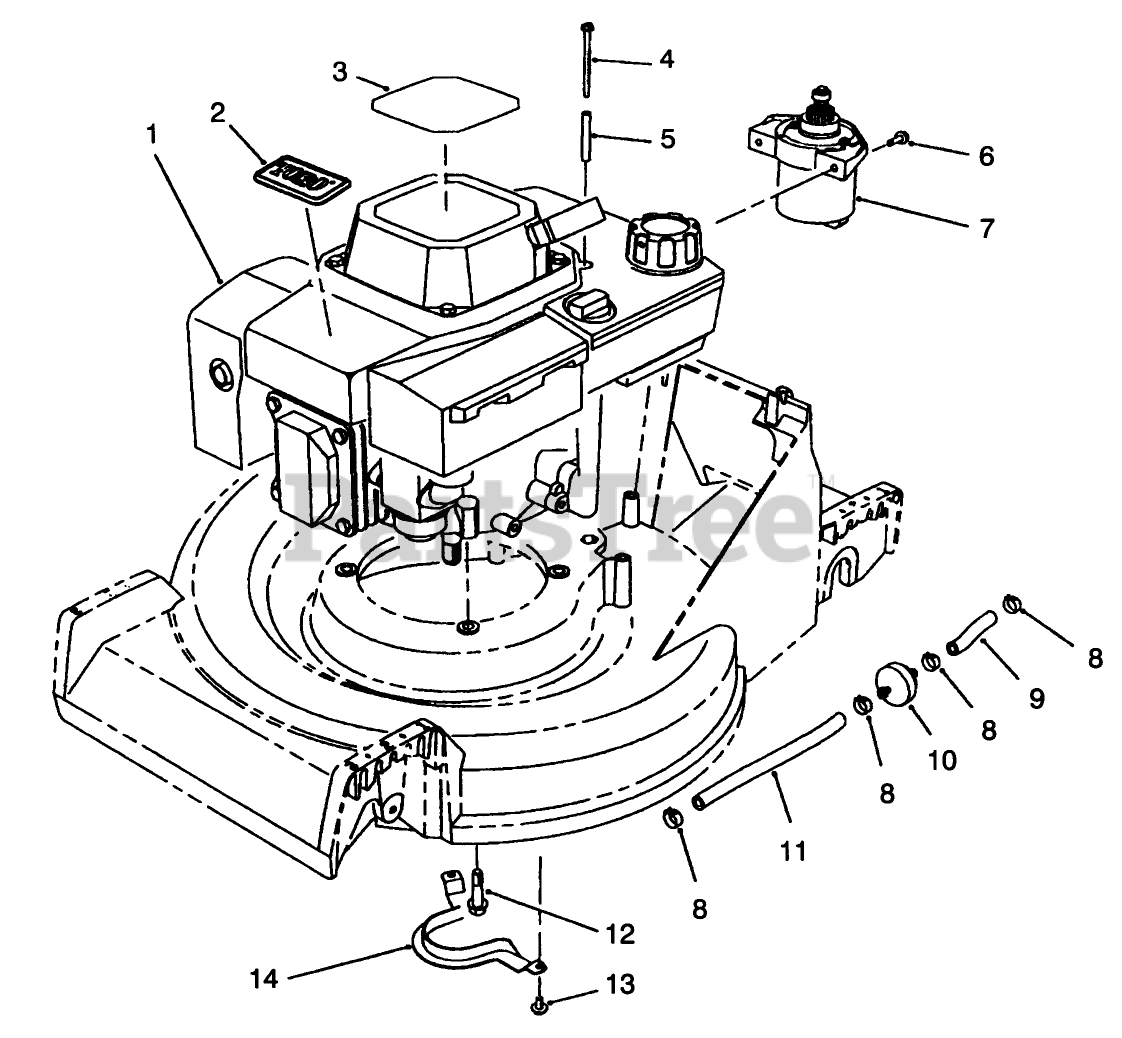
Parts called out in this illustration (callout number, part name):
4	THRD FORMING SCREW
5	TUBULAR SPACER
7	STARTER MOTOR ASM
8	CLAMP-FUEL LINE
9	HOSE-FUEL
10	FILTER-FUEL
11	HOSE-FUEL
12	SCREW-HWH
13	SCREW-HWHTF
